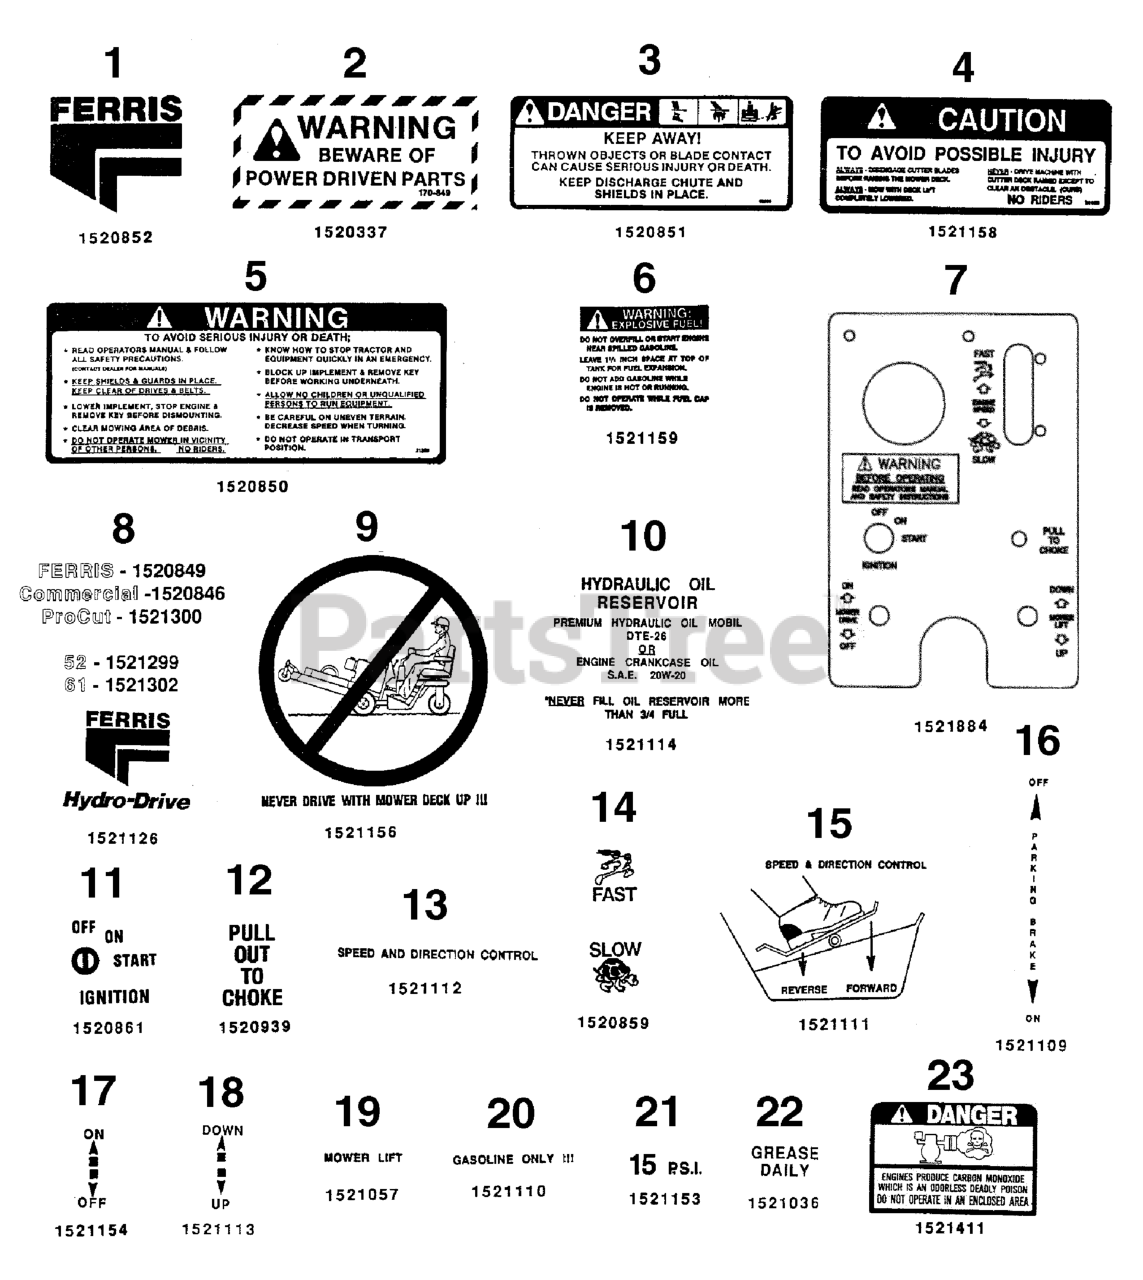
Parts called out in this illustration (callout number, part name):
1	DECAL, Ferris Logo, 10-3/4"
2	DECAL, Warning
3	DECAL, DANGER DO NOT OPERATE W/O DEFLECT
5	DECAL, WARNING Operation
6	DECAL, EXPLOSIVE FUEL
7	DECAL, Operator
8	DECAL, FERRIS TEXT & LOGO
8	DECAL, Commercial
8	DECAL, ProCut
8	DECAL, 52
8	DECAL, 61"
8	DECAL, Hydro Drive
9	DECAL, Never Drive With Mower Deck Up
10	DECAL, Reservior Hydraulic Oil
11	DECAL, Ignition
14	DECAL, Engine Speed
15	DECAL, Speed Control
16	DECAL, PARKING BRAKE-RIDER
17	DECAL, PTO Switch
18	DECAL, PTO Switch
19	DECAL, Mower Lift
20	DECAL, Gasoline Only
21	DECAL, 15 P.S.I.
22	DECAL, Grease Daily
23	DECAL, Danger, Carbon Monoxide
